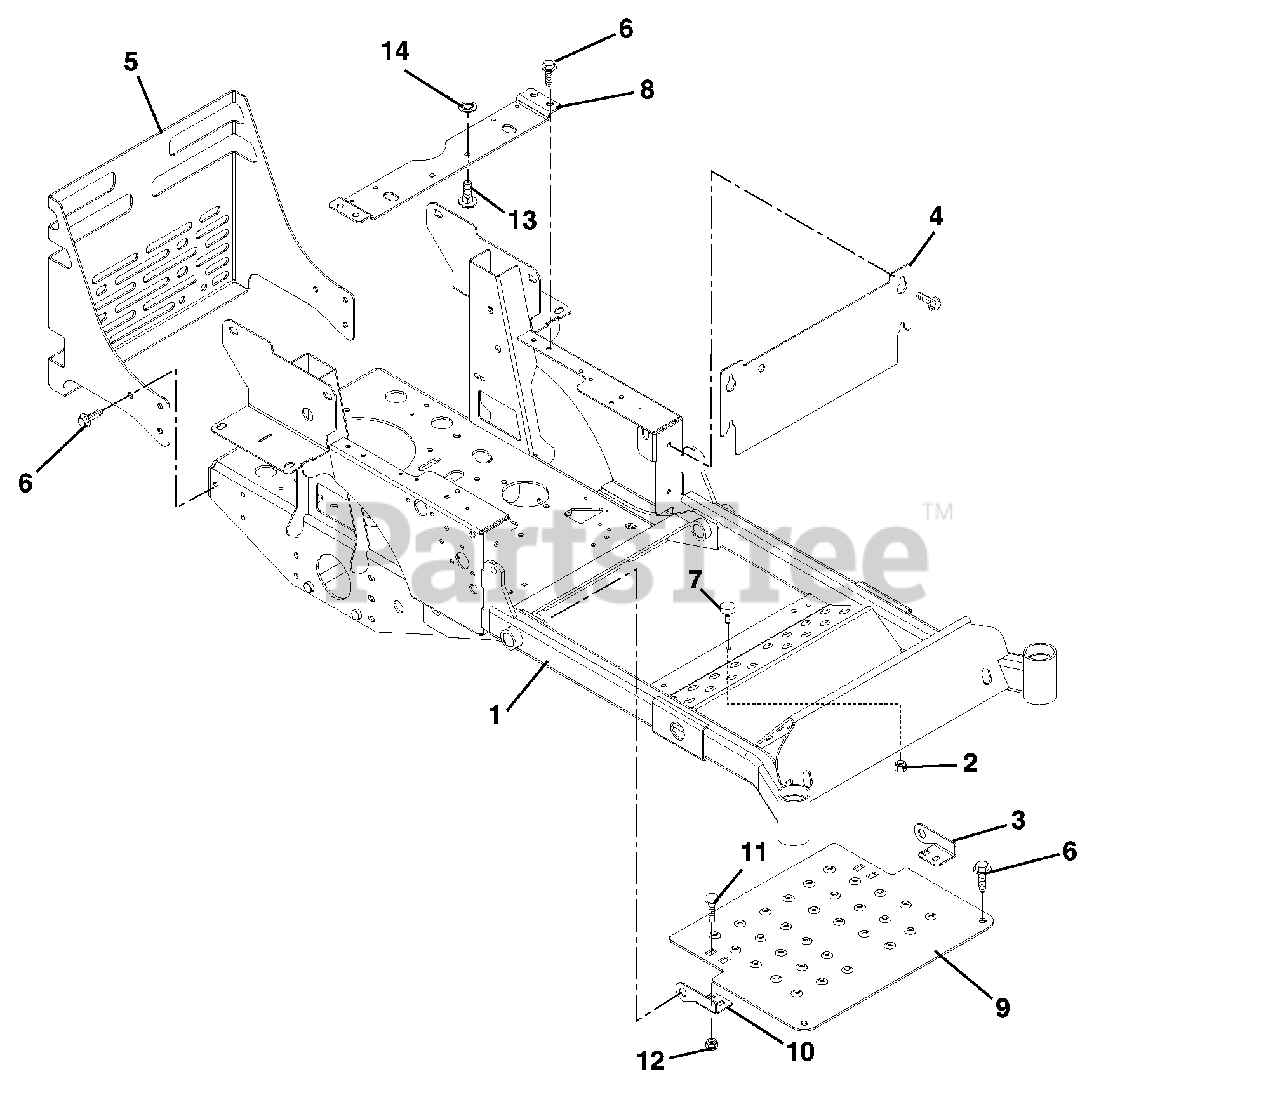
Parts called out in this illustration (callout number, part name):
1	Frame, Compact-Z
2	Nut, Spin Lock Flange .312-18
3	Hinge, Footboard Left Hand
4	Access Panel
5	Bumper, Rear
6	Screw, Tapping .38-16 x .50 Hex Washer Head (056)
6	Screw, Tapping .38-16 x .50 Hex Washer Head (314)
7	Bumper, Rubber
8	Seat Support
9	Footrest Panel
10	Hinge, Footboard Right Hand
11	Bolt, Round Head Square Neck .38-16 x .75 Grade 5
12	Nut, Locking Top Flange .38-16
13	Bolt, Round Head Square Short Neck .31-18 x .75 Grade 5
14	Nut, Push .312
